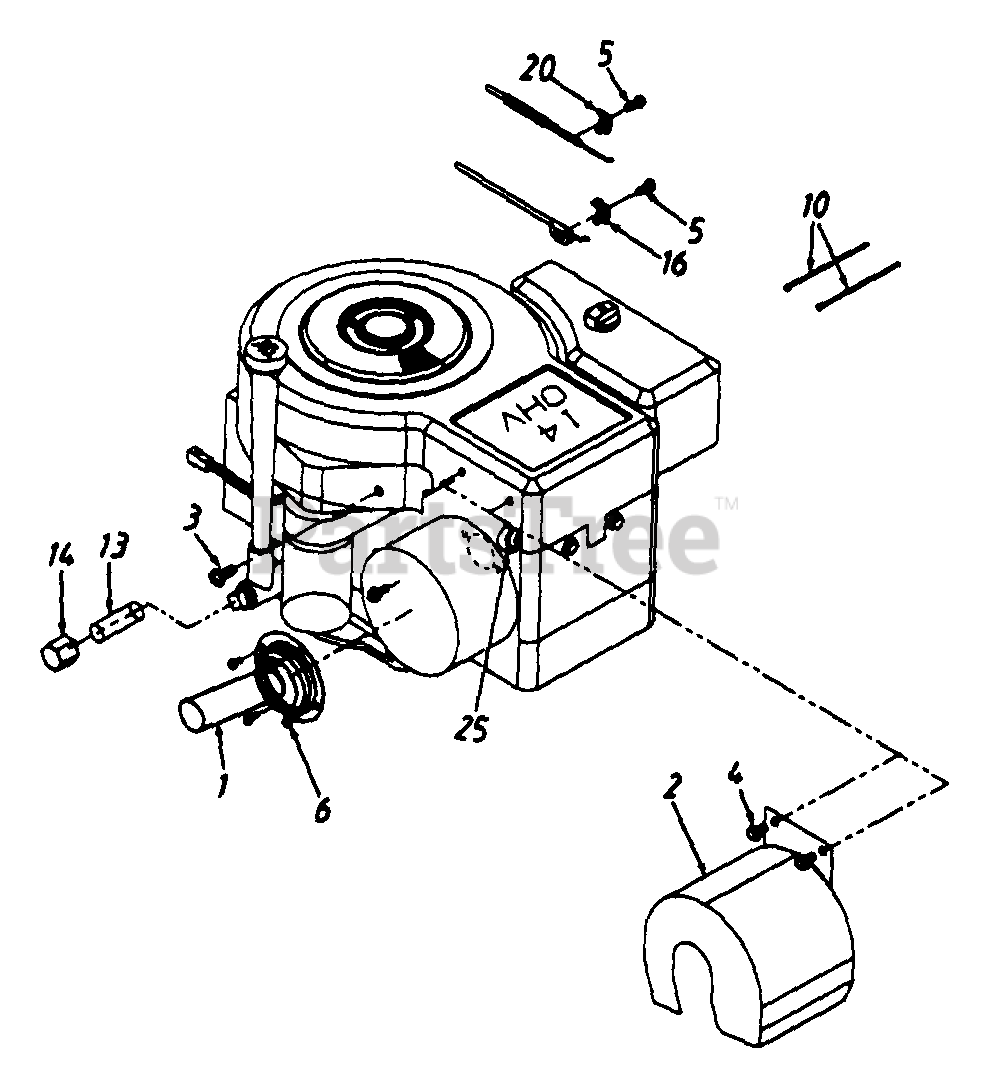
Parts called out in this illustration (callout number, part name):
1	Exhaust Pipe Ass'y.
2	Heat Shield Ass'y.
3	Pan Hd. Mach. Scr. 5/16-18 x .75"
4	Hex Wash. Hd. Scr. 1/4-20 x .5"
5	Hex Slot Wash. Hd. #10 x 5/8" Lg.
6	Hex Wash Hd. F-Tap Scr. #8-32 x .38"
10	Cable Tie-4" I.D.
13	Pipe Nipple 3/8-18 NPT x 2" Lg.
14	Cap - Oil Drain
16	Casing Clamp
20	Casing Clamp
25	Speed Clip (B&S 11, 11.5, 12 & 12.5 H.P.)
